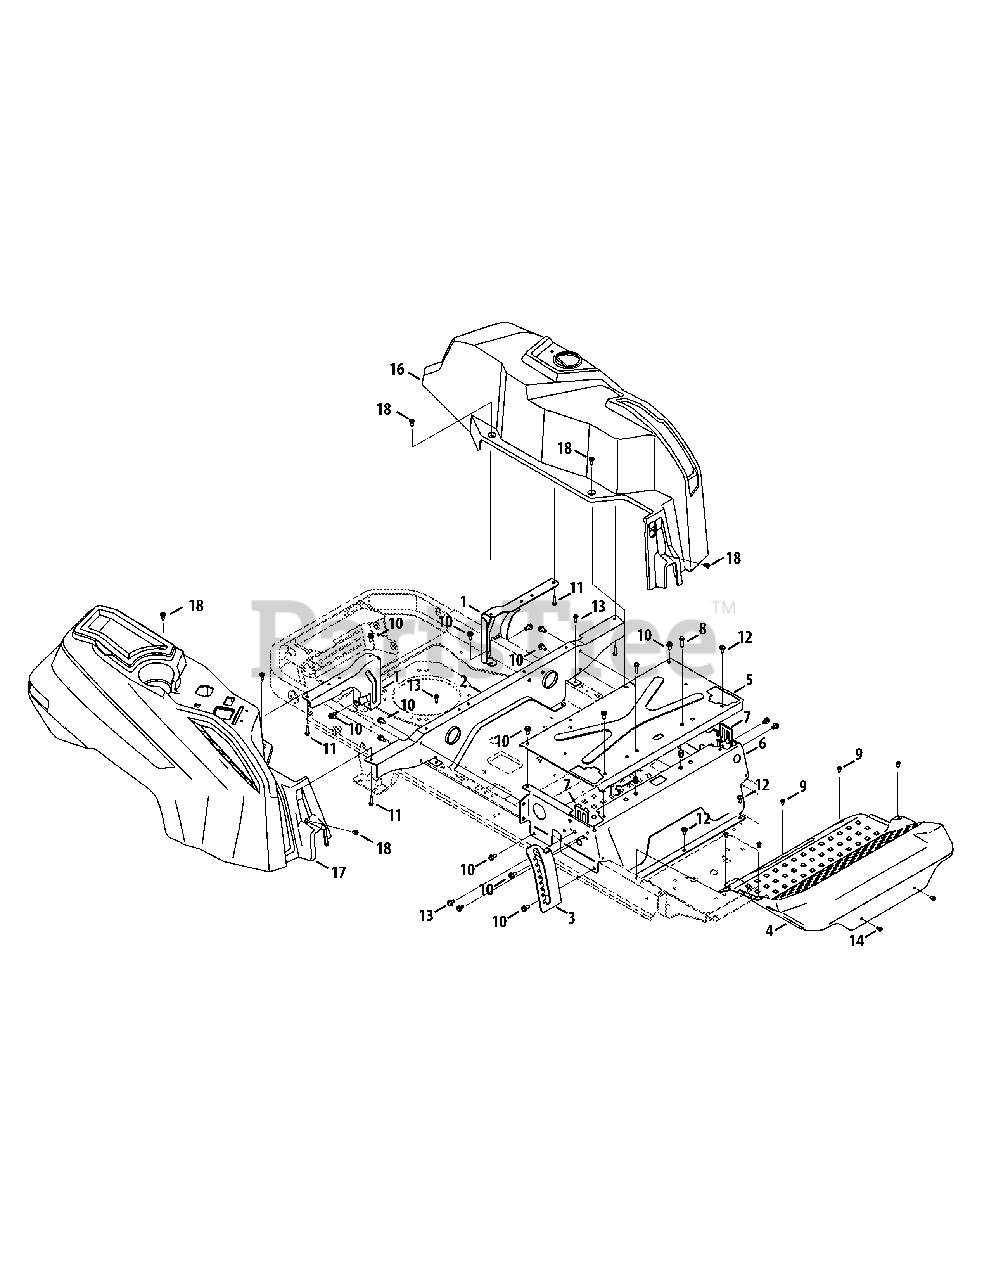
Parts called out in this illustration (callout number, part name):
1	Rear Tank Bracket
2	Rear Seatbox Brace
3	Height Index Bracket
4	Floor Board (Stamped)
5	Seatbox Plate
6	Seat Frame
7	Lapbar Brace Bracket
8	Hex Cap Screw 5/16-18 x 1.00
9	Self Tapping Screw 1/4-20 x .50
10	Hex Washer Screw 5/16-18 x .750
11	Hex Washer Screw 5/16-14 x 1.00
12	Self Tapping Screw 5/16-18 x .750
13	Hex Washer Screw 5/16-18 x .50
14	Self-Tapping Screw 5/16-18, 0.750
15	Nut 5/16-18
16	LH Console
17	RH Console
18	Shoulder Screw 1/4-20
